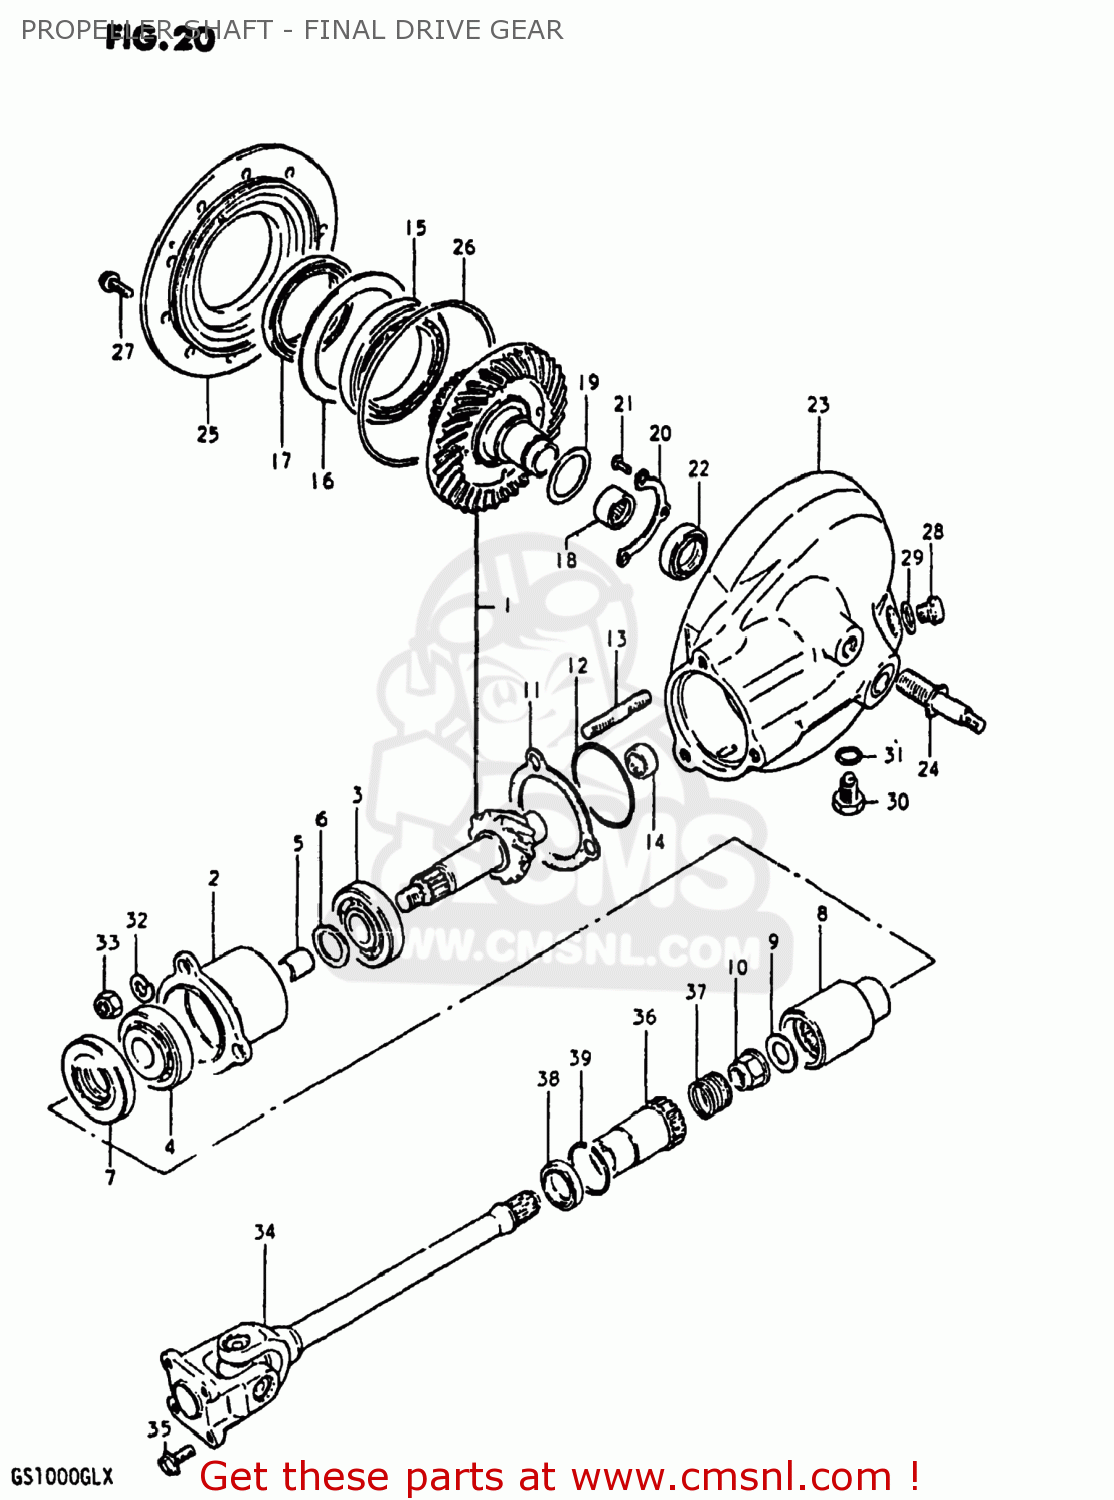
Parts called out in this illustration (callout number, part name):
0	FINAL BEVEL GEAR & CASE
1	GEAR SET,FINAL BEVEL
2	HOUSING,DRIVE GEAR
3	BEARING(25X52X19.25)
4	BEARING
5	SPACER (25.2X30X3.5)
6	SHIM (25X30X2
7	SEAL,OIL(32X54X7)
8	GEAR,FINAL DRIVE
9	WASHER(14X29X4)
10	NUT
11	SHIM,DRIVE GEAR HOUSING
12	O RING(D:2.4,ID:62.6)
13	STUD 10X30
14	BEARING(24X33X17)
15	BEARING(70X110X13)
16	SHIM,DRIVEN GEAR BEARING
17	SEAL,OIL(70X96X16)
18	BEARING(35X48X23.7)
19	SHIM,FINAL DRIVEN GEAR
20	RETAINER,FINAL DRIVEN GEAR BRG
21	SCREW 6X12
22	SEAL,OIL(30X42X7)
23	CASE ASSEMBLY,FINAL GEAR
24	STUD
25	CASE,FINAL GEAR BEARING
26	O-RING (D:3.1 ID:144.4)
27	BOLT
28	PLUG (14X12)
29	GASKET(14X19.2X2) (NAS)
30	PLUG
31	GASKET(14X19.2X2) (NAS)
32	LOCK WASHER
33	NUT
34	SHAFT ASSEMBLY,PROPELLER
35	BOLT(8X17)
36	COUPLING,PROPELLER SHAFT
37	SPRING
38	SEAL,OIL(30X40.5X5.5)
39	CIRCLIP
